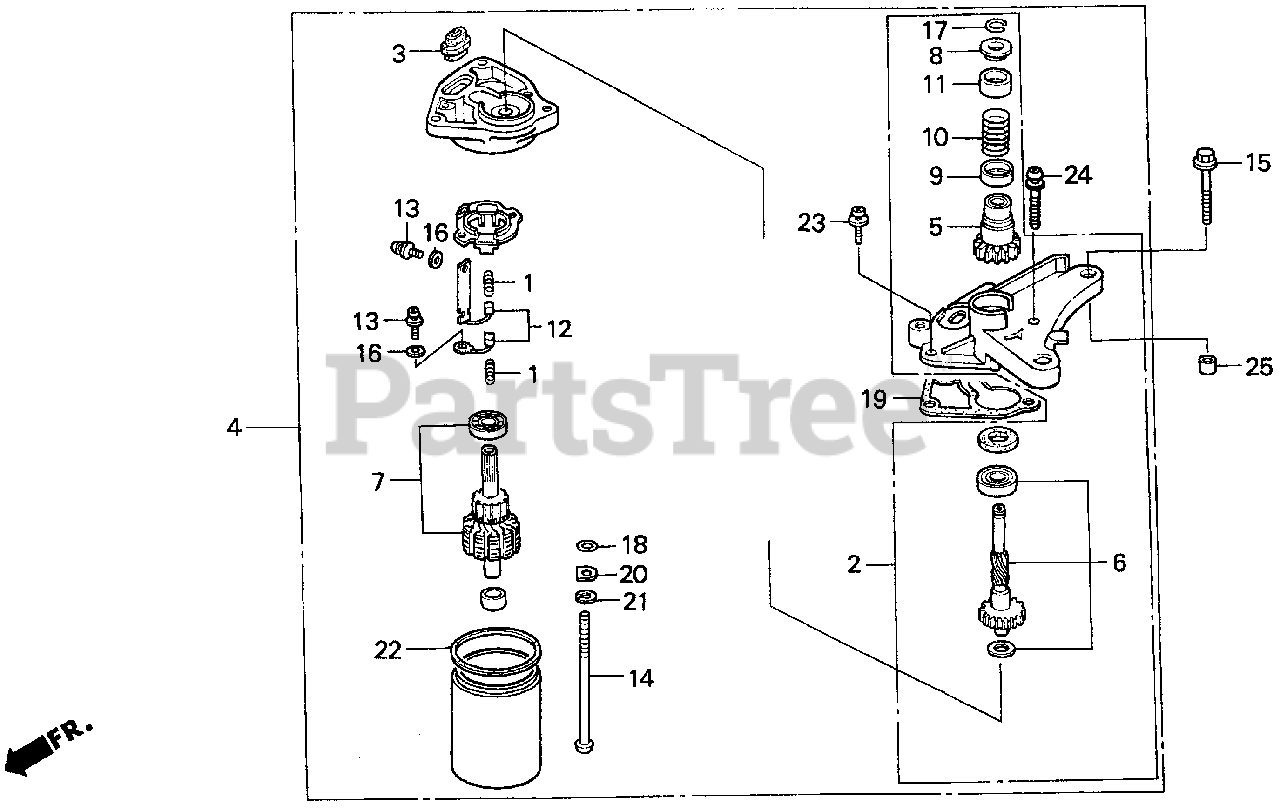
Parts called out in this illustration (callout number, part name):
1	SPRING, BRUSH
2	COVER, GEAR
3	GROMMET
4	MOTOR ASSY., STARTER
5	GEAR, PINION (16T)
6	SHAFT SET, GEAR
7	ROTOR ASSY.
8	PIECE A, STOPPER
9	PIECE B, STOPPER
10	SPRING, RETURN
11	COVER, SPRING
12	BRUSH SET
13	SCREW-WASHER (3X8)
14	BOLT, SETTING
15	BOLT, FLANGE (6X32)
16	WASHER, SPECIAL
17	CIRCLIP (7.1MM)
18	O-RING
19	GASKET
20	WASHER, SPECIAL
21	WASHER, SPRING
22	GASKET
23	SCREW-WASHER (5X16)
24	SCREW-WASHER (5X3)
25	PIN A, DOWEL (8X14)
